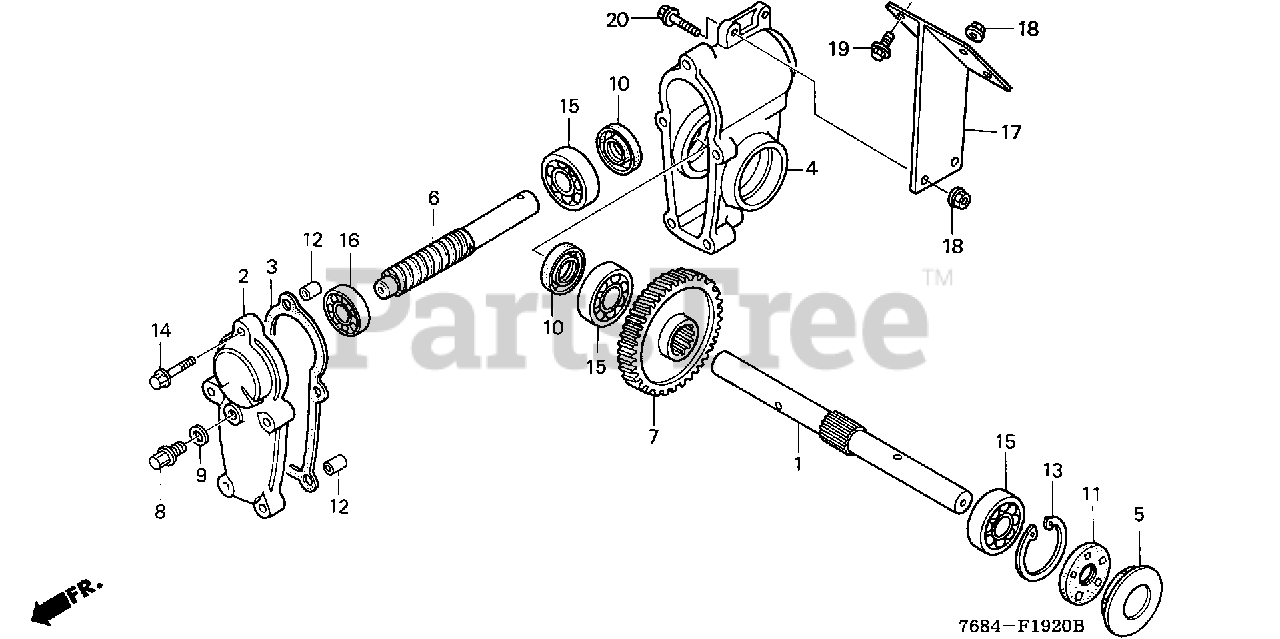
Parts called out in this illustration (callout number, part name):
1	SHAFT, AUGER
2	COVER, AUGER TRANSMISSION
3	GASKET, AUGER TRANSMISSION
4	CASE, AUGER TRANSMISSION
5	CAP, AUGER CASE
6	GEAR, DRIVE
7	GEAR, DRIVEN (55T)
8	BOLT, DRAIN PLUG
9	WASHER, DRAIN PLUG (10.2MM)
10	OIL SEAL (20X32X7)
11	OIL SEAL (20X42X8)
12	PIN, DOWEL (8X14)
13	CIRCLIP (INNER) (42MM)
14	BOLT, FLANGE (6X32)
15	BEARING, RADIAL BALL (6004)
16	BEARING, RADIAL BALL (6202)
17	BRACKET, AUGER HOUSING
18	NUT, FLANGE (8MM)
19	BOLT, FLANGE (8X14)
20	BOLT, FLANGE (8X25)
